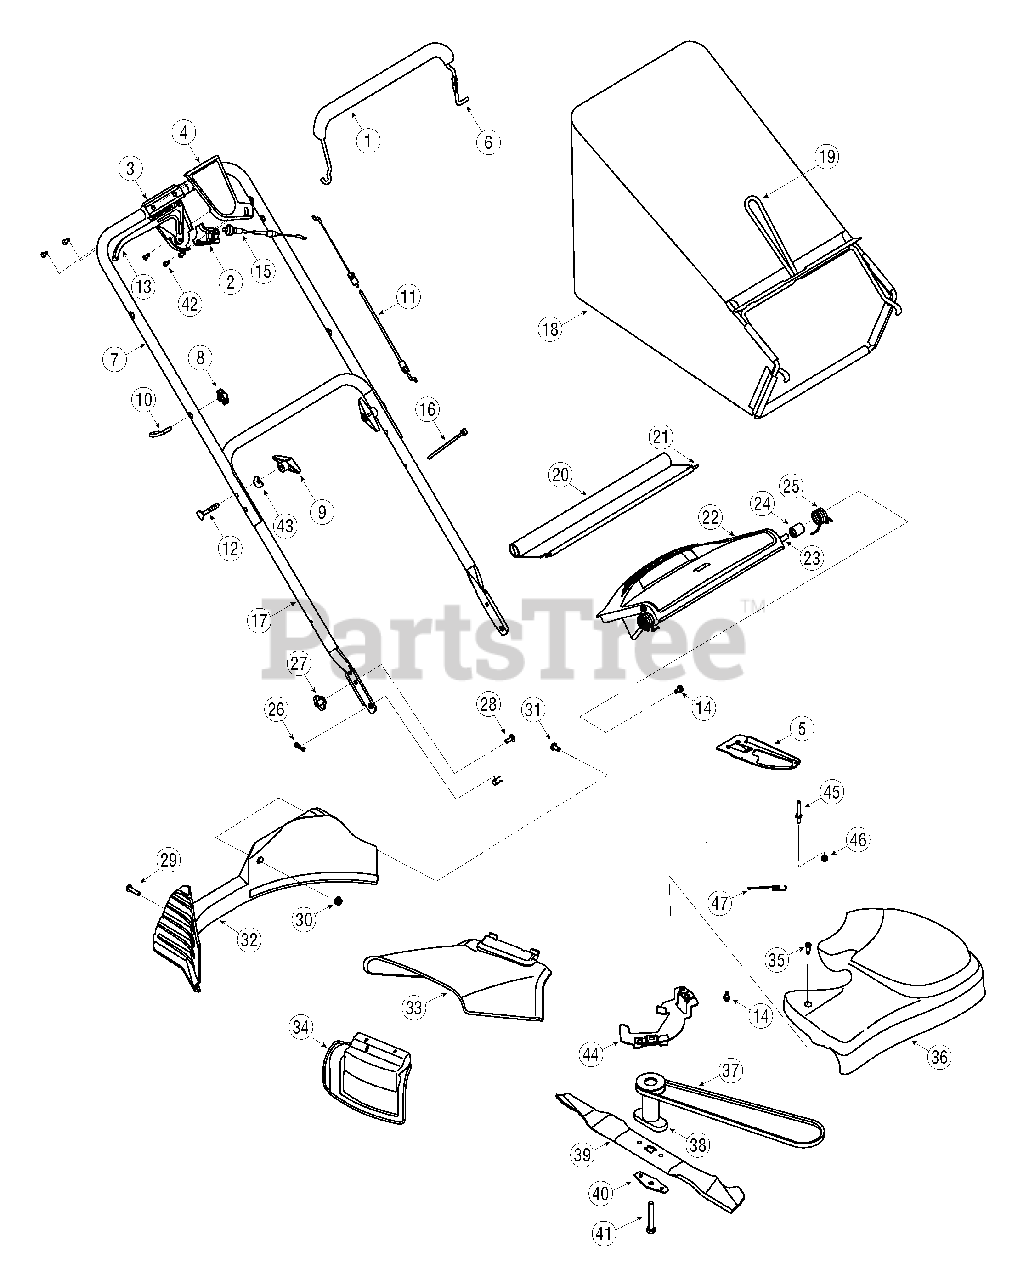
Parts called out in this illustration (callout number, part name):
1	Deluxe Bail Cover
2	Cable Mounting Cap
3	Control Cover Lower Half
4	Control Cover Upper Half
9	Handle Knob
11	Control Cable 37.25"
12	Carriage Bolt 5/16-18 x 2.0
13	Drive Control Lever
14	TT Screw 1/4-20 x 0.5
15	Drive Cable
16	Cable Tie
18	Grassbag Assembly
20	Rear Trailing Shield
21	Wire
22	Rear Discharge Door
23	Pivot Rod
24	Spacer.375 x.50 x 1.02
25	Torsion Spring LH
26	Cotter Pin
27	Wing Nut
28	Carriage Bolt 1/4-20
29	Machine Screw 1/4-20
30	Flange Lock Nut 1/4-20
31	HL Screw 1/4-15
32	Rear Baffle 21" Rd.
33	Chute Deflector
34	Mulch Plug Comp.
35	Shoulder Screw # 12 -24
36	Transmission Cover
37	V-Belt
38	Blade Adapter w/ Pulley
39	21" Mulching Blade
40	Blade Bell Support
41	Hex Screw 3/8-24 x 2.50
42	HL Screw #10-16
43	Saddle Washer
45	Belt Guard Pin 1/4 x 1.43
46	Hex Lock Nut 1/4 x 20
47	Extension Spring
